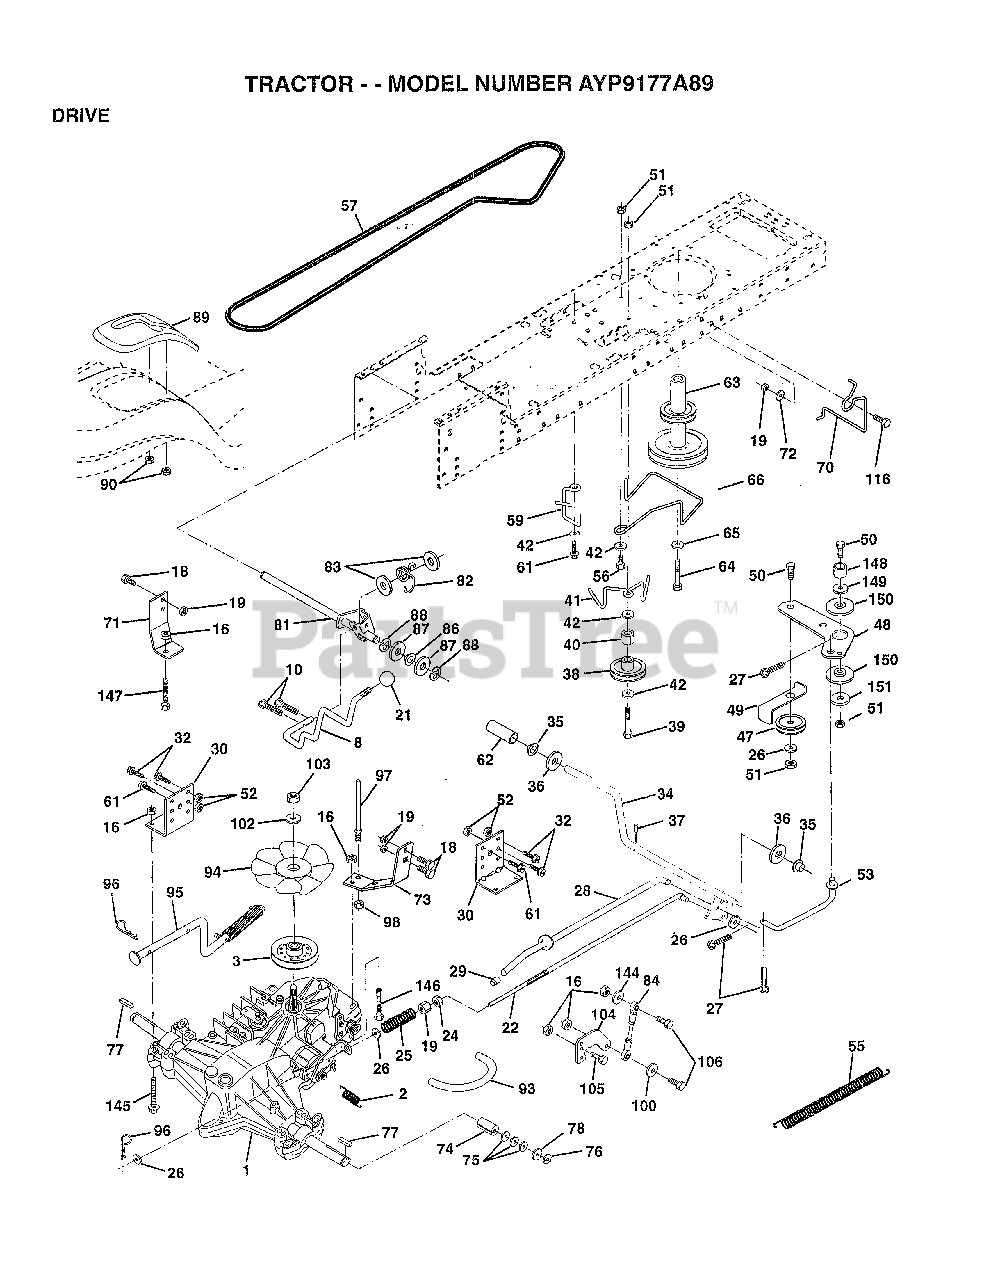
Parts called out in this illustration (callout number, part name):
1	TRANSAXLE.3100650
2	SPRING RET BRAKE
3	PULLEY.TRANSAXLE
8	"ROD SHIFT,FENDER"
10	PIN COTTER 1/8
16	NUT
18	BOLT
19	NUT
21	KNOB T (1/2-HOLE)
22	ROD.BRAKE.HYDRO.
24	NUT
25	SPRING ROD LT
26	WASHER
27	COTTER PIN
28	ROD.BRAKE.PARK.LT
30	TRANSAXLE MTG BKT
32	BOLT
34	SHAFT ASM-PEDAL F
35	NYLON BEARING
36	WASHER LT
38	PULLEY.IDLER.FLAT
39	BOLT
40	SPACER T
42	WASHER
48	BELLCRANK.CLUTCH
49	RETAIN BELT
53	"LINK, CLUTCH T"
55	"SPRING, RETURN LT"
57	V-BELT.GROUND.HYD
59	KEEPER BELT CNTSP
61	SCREW
62	PEDAL COVER T
63	PULLEY.ENGINE
64	BOLT
65	LOCKWASHER
66	ENGINE BELT KEEPR
71	STRAP TORQ LH HYD
72	WASHER
73	"STRAP-TORQUE,RH"
74	SPACER SPLIT
76	E-RING LT
77	SQUARE KEY
78	WASHER
81	SHAFT.ASM.CROSS
82	"SPRING,TORSION"
83	WASHER
84	ROD.TIE
86	BUSHING
87	WASHER D
88	KLIP RING
90	NUT
93	"LINE FUEL HYD 4"""
94	"FAN 7"" HYDRO"
97	BOLT KEEPER RH
98	NUT
100	WASHER M
102	WASHER BELLEVILLE
104	ARM CONTROL HYDRO
105	SCREW CAP 5/16-18
106	BOLT
116	BOLT RDHD 3/8-16
144	WASHER
145	BOLT.HEX.FLGHD
146	BOLT.HEX.FLGHD.
147	BOLT.HEX.FLGHD
149	SPACER RETAINER
150	BUSHING.NYLON
151	WASHER
